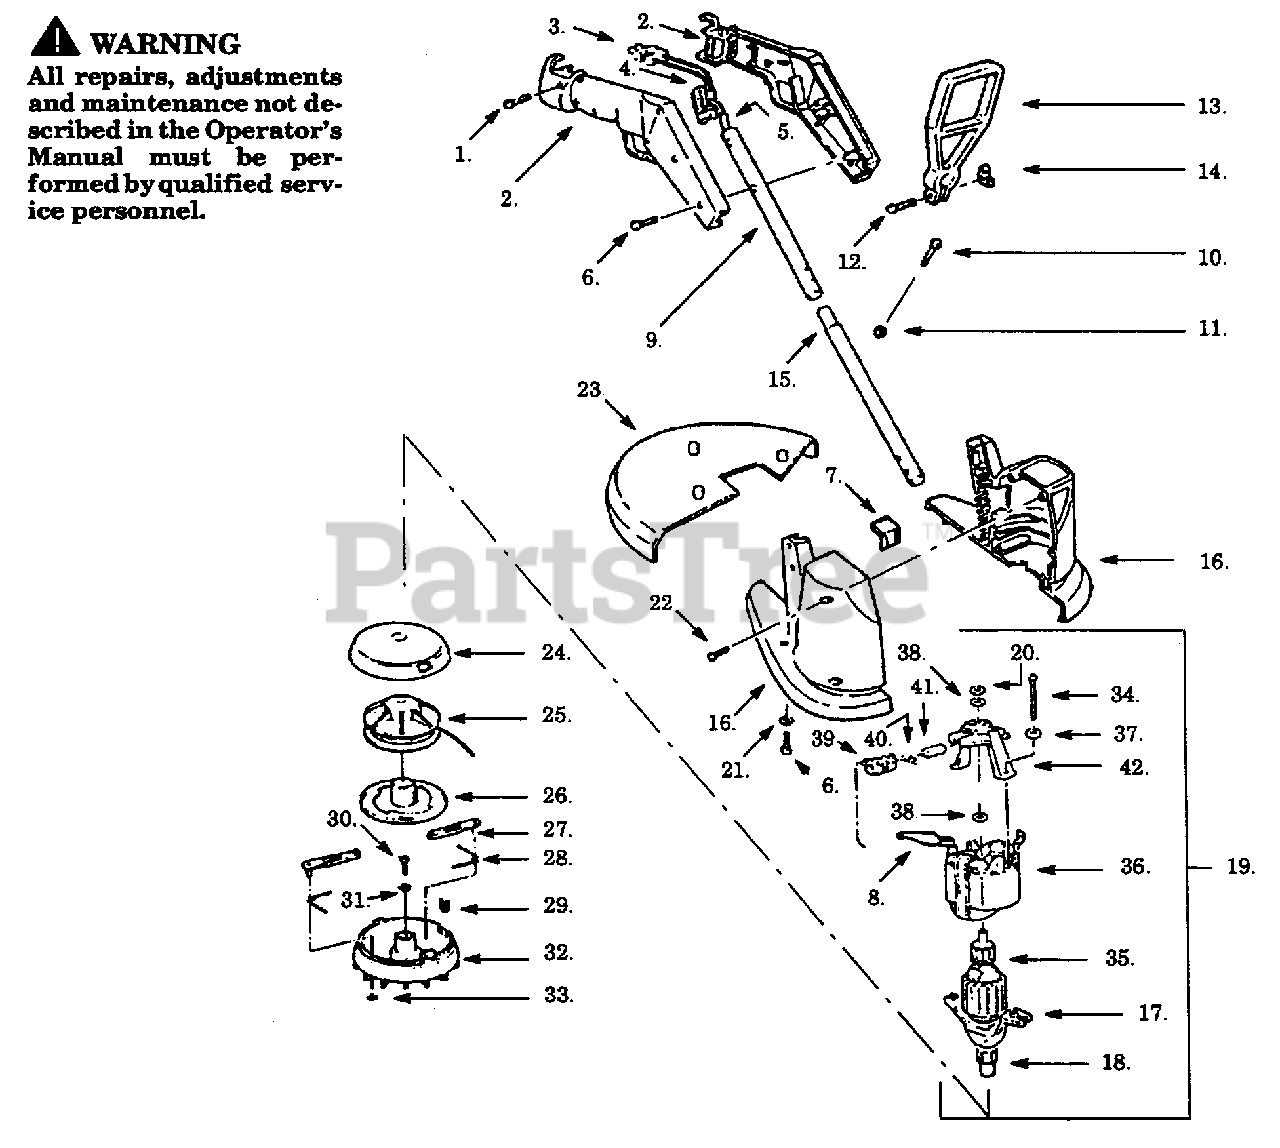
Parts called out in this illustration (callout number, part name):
2	Handle Set
4	Trigger Switch
5	Harness Assembly
7	Line Cutter
8	Lead Wire
9	Upper Handle Tube
13	Assist Handle
16	Housing Set
17	Endbell - Drive
18	Shaft Adaptor
19	Motor Assembly
20	Retaining Ring
25	Spool w/Line
29	Line Saver
32	Housing Ass'y. (Inc. 27,28,29,32,33)
35	Armature/End Bell
36	Field Ass'y
39	Brush Holder Ass'y
42	End Bell Ass'y
